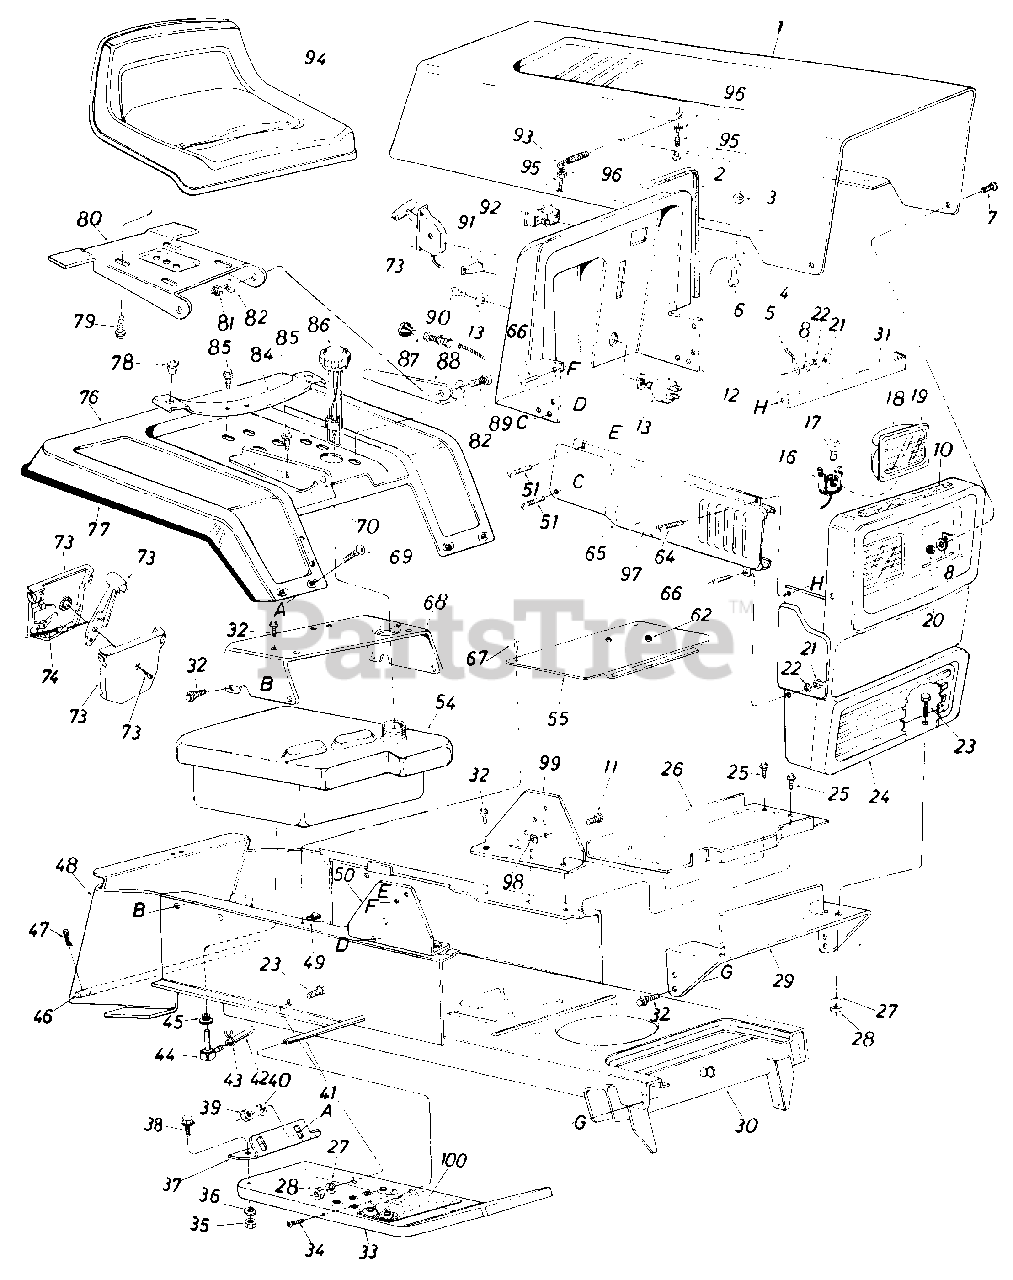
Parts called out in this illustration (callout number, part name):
1	Hood
2	Vinyl Molding Strip 27"
3	Hex Sems Nut #10-24 Thd.
4	Fl-Wash. .20" I.D. x .41" O.D.
5	Hood Stop
6	Truss Hd. Mach. Scr. #10-24 x .50" Lg.
7	Hex Bolt 1/4-20 x .62" Lg.
8	Fl-Wash. 1/4" I.D.
10	Foam Strip 3/8" x 3/4" x 14"
11	Truss Mach. B-Tap Scr. #10 x 1/2" Lg.
12	Dash Ass'y.
13	Ignition Switch
16	S ockel
17	Lamp
18	Headlight Housing
19	Lens
20	Hex L-Nut 1/4-20 Thd.
21	Hex Nut 1/4-20 Thd.
22	L-Wash. 1/4" I.D.
23	Hex Bolt 5/16-18 x .75" Lg.
24	Grille
25	Hex Wash. Hd. AB-Tap Scr. 1/4 x .50" Lg.
26	Battery Plate
27	L-Wash. 5/16" I.D.*
28	Hex Nut 5/16-18 Thd.
29	Grille Mounting Bracket
30	Lower Frame Ass'y.
31	Tie Strap Grille/Side Panel
32	Hex Thd. Rolling Scr. 5/16-24 x .75" Lg.
33	Running Board R.H.
34	Truss Mach. Scr. 5/16-18 x .75" Lg.
35	Hex Nut 5/16-18 Thd.
36	Bell-Wash. .34" I.D.
39	Hex Nut 1/4-20 Thd.
40	L-Wash. 1/4" I.D.
41	Running Board Rod
42	Fuel Line 44" Lg.
43	Hose Clamp 3/8
44	90ø Nipple
45	Bushing
46	Hitch Rod
47	Internal Cotter Pin
48	Hitch Plate
49	Speed Nut
50	Dash Support Brk't. R.H.
51	Hex Wash. Hd. Tap Scr. 1/4 x .75" Lg.
54	Fuel Tank
55	Transmission Cover Ass'y.
62	Snap Bushing
64	Truss Hd. Scr. 1/4-20 x .75" Lg.*
65	Side Panel R.H.
66	Truss Mach. Scr. 1/4-20 x .50" Lg.*
67	Truss Mach. B-Tap Scr. #10 x .50" Lg.
68	Seat Mounting Channel
69	Carriage Bolt 1/4-20 x .50" Lg.*
70	Seat Bracket R.H.
73	Throttle Control Box Ass'y.
74	Throttle Control Wire
78	Grommet
79	Hex Wash. Hd. AB-Tap Scr. 3/8 x .75" Lg.
80	Seat Pivot Bracket
81	Hex Cent. L-Nut 5/16-18 Thd.
82	Belleville Wash. .34" I.D. x .88" O.D.
84	Seat Spring
85	Hex Wash. Hd. Self-Tap Scr. 5/16-18 x .50" Lg.
86	Gas Cap w/Gauge
87	Choke Control Comp.
88	Seat Bracket L.H.
89	Hex Bolt 5/16-18 x .75" Lg.*
90	Ignition Key
91	Light Switch
92	Ammeter
93	Hood Spring
94	Seat Ass'y.
95	Hex Bolt #10-24 x 1.0" Lg.
96	Hex Top L-Nut #10-24
97	Rubber Strip 1/2" x 21/2" Lg.
98	Speed Nut #10-24
99	Dash Support Brk't. L.H.
100	Foot Pad
